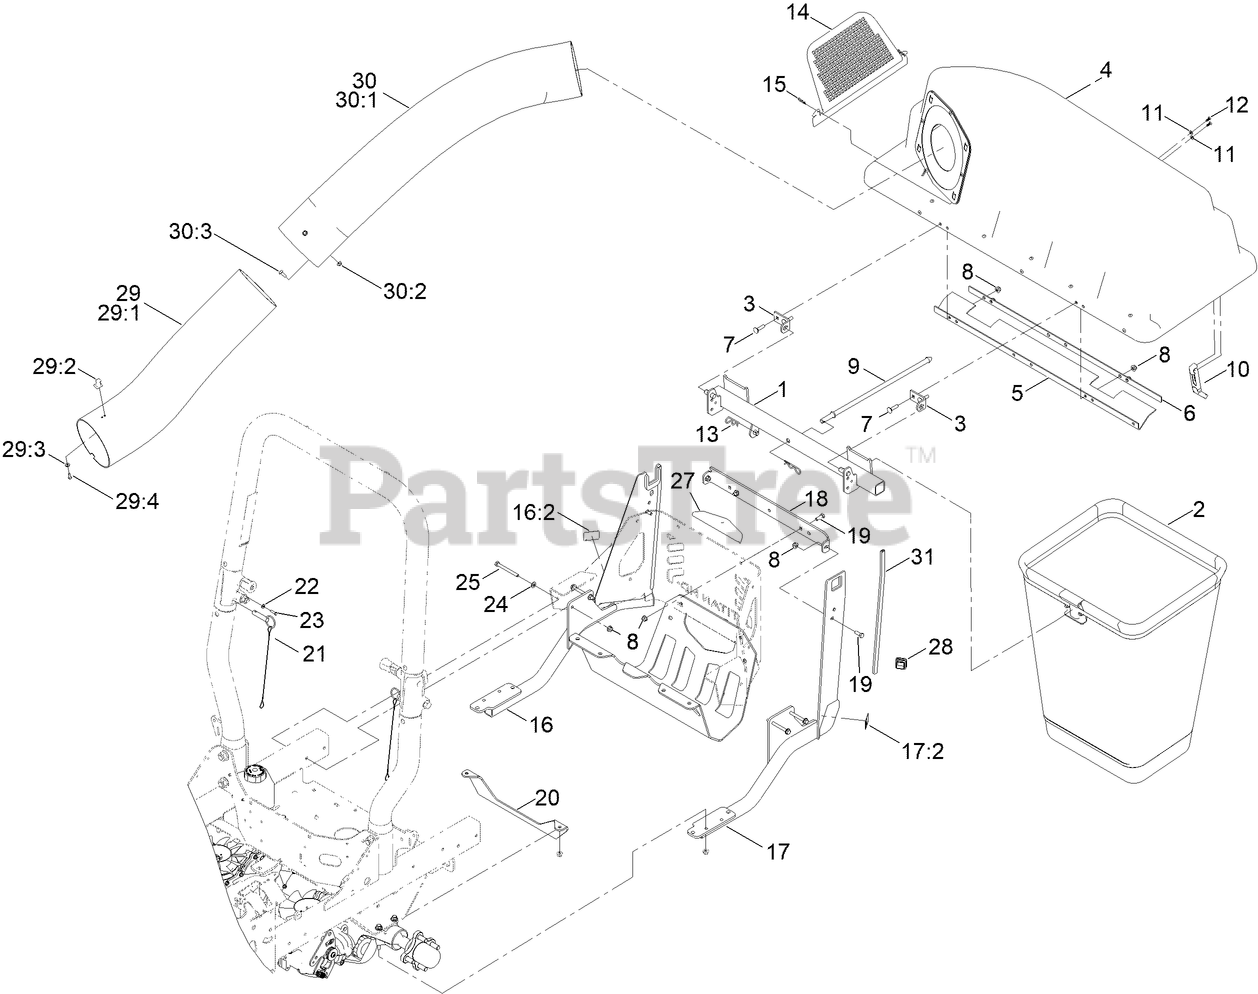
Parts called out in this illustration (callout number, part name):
1	FRAME PIVOT ASM
2	BAG AND FRAME ASM
3	BRACKET-PIVOT, HOPPER
4	BAGGER HOOD ASM
6	PLATE-BACKING
7	SCREW-CARR
8	NUT-HF, NI
9	ROD-HOLD DOWN, HOOD
10	LATCH-RUBBER
11	WASHER-FLAT
12	SCREW-PLASTITE
13	PIN-HAIR
14	SCREEN-BAGGER
16	RH BAGGER SUPPORT ASM
16:2	DECAL-WARNING
17	LH BAGGER SUPPORT ASM
17:2	DECAL-WARNING
18	ANGLE - SUPPORT, BAGGER
19	SCREW-HH
20	SUPPORT-TRANSMISSION
21	HITCH PIN ASM
22	WASHER-FLAT
23	SCREW
24	WASHER-PLAIN
25	SCREW-HH
27	COVER-HITCH
29	LOWER TUBE ASM
29:1	TUBE-LOWER
29:2	LATCH-KEEPER
29:3	WASHER-FLAT
29:4	SCREW-PPH
30	UPPER TUBE ASM
30:1	TUBE-UPPER
30:2	NUT-HF
31	STRIP-TRIM
